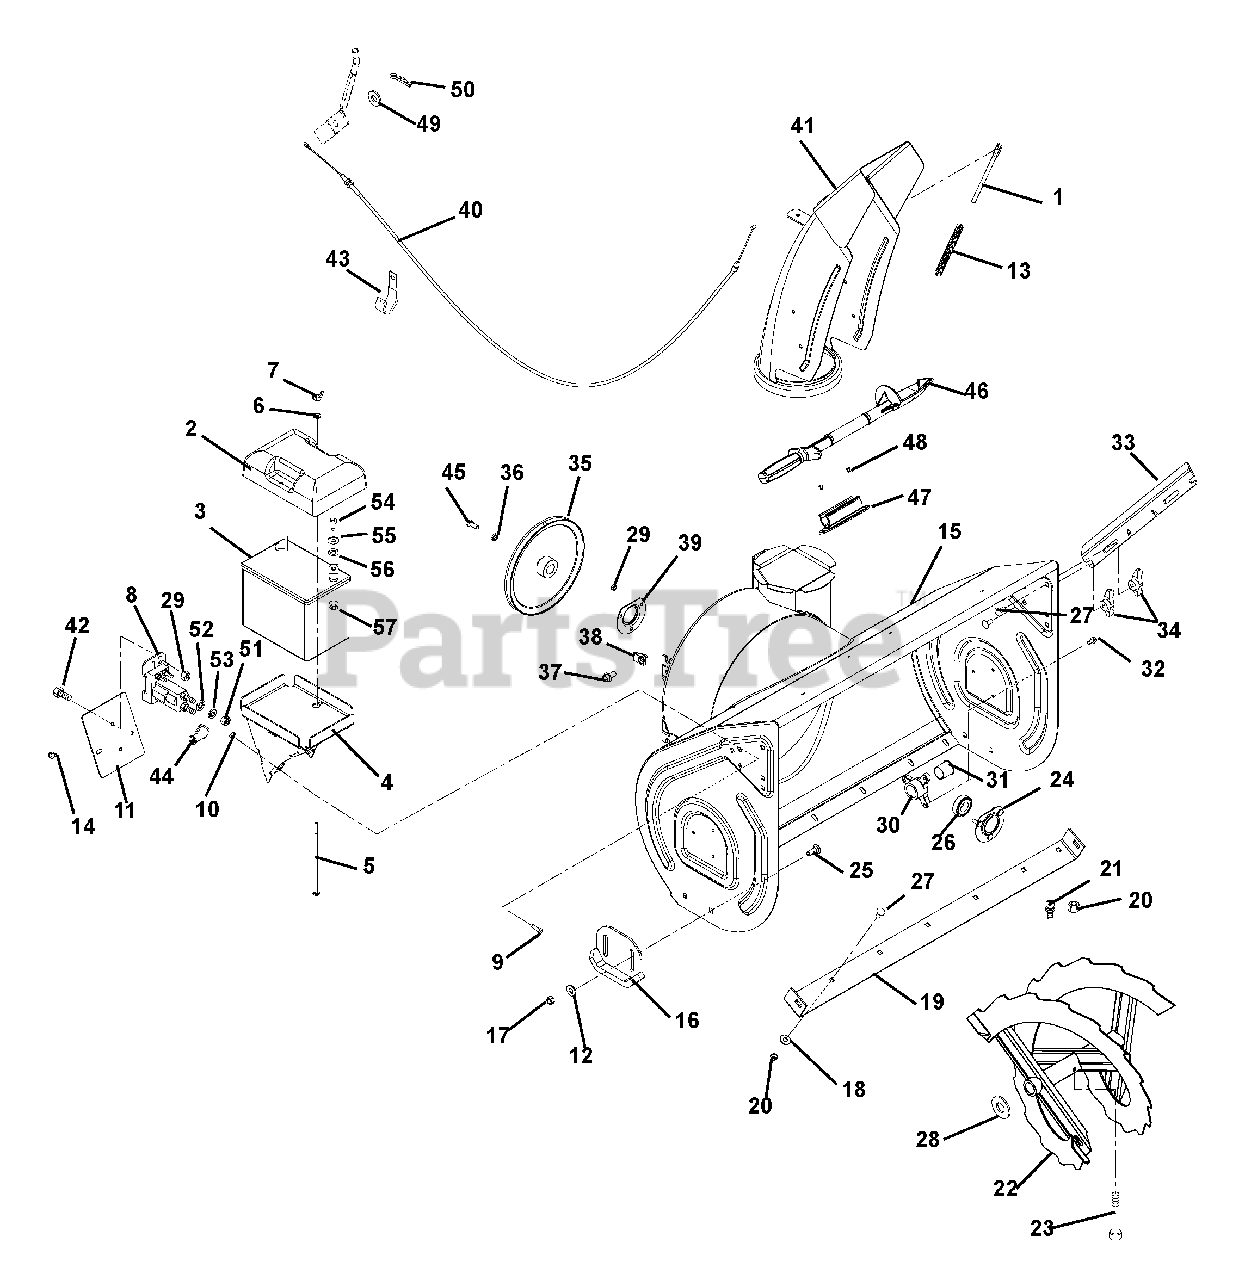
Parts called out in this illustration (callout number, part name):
1	ROD, DEFLECTOR CAP
2	COVER, BATTERY
4	TRAY, BATTERY
5	@BLT-RDHDSQNK .25-20X7.00 G2YZ
6	@WSHR-FL-STL.281X.62X.065 YWZC
7	NUT-LK WING .250-20 YWZC
8	SOLENOID
9	@BLT-HEX .25-20X.75 GR5 YWZC
10	@NUT-SPNLK-FLG .25-20 YWZC
11	COVER, SOLENOID
12	@WSHR-FL-STL.438X1.00X.083 YWZ
13	SG-COMP .08X.40X6.50 14#/IN
14	@SCR-TAP .25-20X.50 HWH TR YWZ
15	HOUSING, BLOWER-26" W/DECAL
15	HOUSING, BLOWER-28" W/DECAL
15	HOUSING, BLOWER-32" W/DECAL
15	HOUSING, BLOWER-32"BAT W/DECAL
15	HOUSING, BLOWER-36" W/DECAL
16	RUNNER, SKID SHOE-1/2" FLANGE
16	SKID SHOE, REVERSIBLE - ORANGE
17	@NUT-LK-CTR .38-16 YWZC
18	@WSHR-FL-STL.438X1.00X.083 YWZ
18	@WSHR-FL-STL.38X.875X.083 YWZC
19	BLADE, SCRAPER-26"
19	BLADE, SCRAPER-28"
19	BLADE, SCRAPER-32"
19	BLADE, SCRAPER-36"
20	@NUT-LK-CTR .31-18 YWZC
21	FTG-LUBE .25-28X.256 YWZC
22	RAKE, LH-26"(1 ID X 15.75 OD)
22	RAKE, RH-26" (1 ID X 15.75 OD)
22	RAKE, LH-28" (1 ID X 15.75 OD)
22	RAKE, RH-28" (1 ID X 15.75 OD)
22	RAKE, LH-32" (1 ID X 15.75 OD)
22	RAKE, RH-32" (1 ID X 15.75 OD)
22	RAKE, LH-36" (1ID X 15.75 OD)
22	RAKE, RH-36" (1 ID X 15.75 OD)
23	SHEAR BOLT SERVICE ASSEMBLY
24	BEARING FLANGE
25	@BLT-RDHDSHSQNK.38-16X1.0 G5YZ
26	BRG-BALL .876 X 1.750 X .50
27	@BLT-RHDSSQNK .31-18X.75 G5YZ
28	WSHR-FL-STL 1.010X1.505X.062YZ
29	@NUT-LK-CTR .25-20 YWZC
30	BUSHING, RAKE SHAFT 1"
31	BSHG-FLG, SPLIT NYLINER 1.0"ID
32	@SCR-TAP .25-20X.50 HWH TR YWZ
33	CUTTER, DRIFT
34	KNOB - WING .312-18 UNC
35	PULLEY, 4L W/HUB, .87 X 8.5
36	WSHR-LK .312X.097 HVY YWZC
37	BLT-SERHFWH .38-16X.75 YWZC
38	NUT-RTNR .375-16X.37
39	BEARING FLANGE
40	CABLE, DEFLECTOR
41	CHUTE, DISCHARGE-W/DEFLECTOR
42	@BLT-HEX .25-20X.50 GR5 YWZC
43	J-CLAMP
44	BOOT, EYELET TERMINAL
45	BLT-HEX .31-24X.75 YWZC GR5
46	DEVICE, SNOW CLEAN OUT
47	MOUNT, SNOW CLEAN OUT
48	RVT-POP .187X.45 DOME SS FBF64
49	@WSHR-FL-STL.281X.62X.065 YWZC
50	PIN-HAIR INT .06X.18X.77
51	NUT-JAM .31-24 YWZC
52	WSHR-LOCK INT .31 YWZC
53	@WSHR-LK .31X.078 REG YWZC
54	@BLT-HEX .25-20X.75 GR5 YWZC
55	WSHR-FL-STL .265X.50X.087YWZC
56	@WSHR-LK .25X.062 REG YWZC
57	@NUT-HEX .25-20 YWZC
